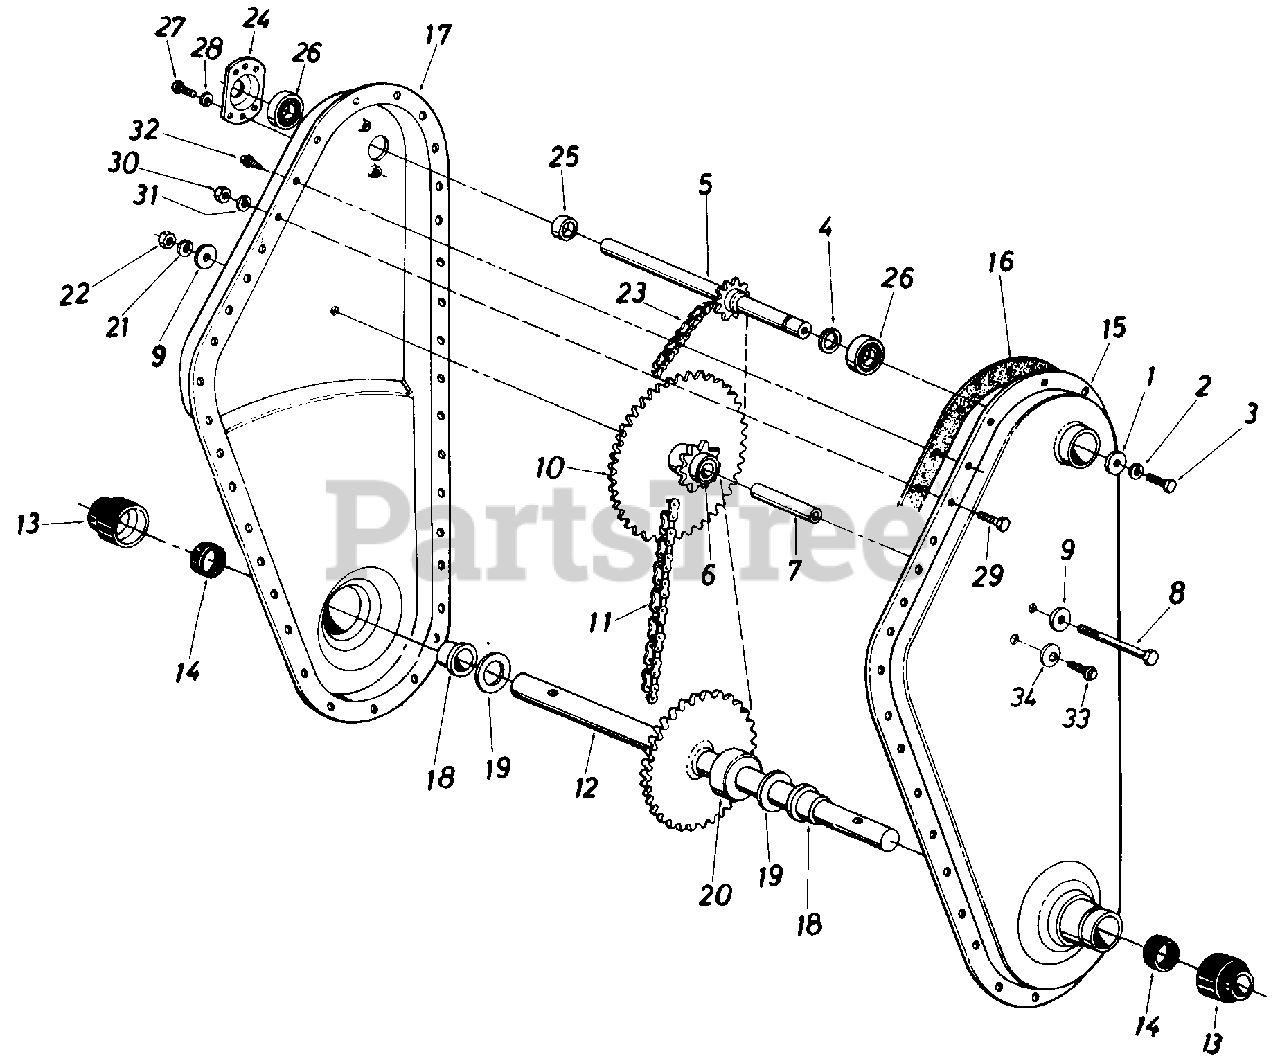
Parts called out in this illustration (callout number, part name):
1	Fl-Wash. 1/4" l.D. x .93" O.D. x .120
2	L-Wash. 1/4" I.D.
3	Hex Bolt 1/4-28 x .62" Lg. w/Patch
4	Extemal Snap Ring-5/8" Dia.
5	Input Shaft Ass'y.
6	Bearing 618" l.D. x 3/4" O.D. x 1.860" Lg.
7	Sprocket Hub Tubing 3/8" l.D. x 618" O.D. x 1.90
8	Hex Bolt 3/8-24 x 2 75" Lg.
9	Fl-Wash. 3/8" l.D. x 1.25" O.D. x .10
10	Sprocket Ass'y.
11	#50 Chain 5/8" Pitch x 46 Links Endless
12	Tine ShaR Ass'y.
13	Dust Cup
14	Seal Ring Single Lip, Springless
19	Fl-Thrust Wash. 1.0" I.D. x .03 Thk.
20	Step Spacer
21	L-Wash. 3/8" I.D.
22	Hex Nut 3/8-24 Thd.
23	#35 Chain 3/8" Pitch x 52 Links Endless
24	Bearing Housing 1.38" I.D.
25	Spacer
26	Ball Bearing .625" l.D. x 1.38 O.D. x .437
27	Hex Wash. SF-Tap Scr. 1/4-20 x .501' Lg.
28	L-Wash. 1/4" l.D.
29	Hex Bolt 5/16-18 x .75" Lg.
30	Hex Nut 5/16-18 Thd.
31	L-Wash. 5/16" I.D.
32	Hex Wash. SF-Tap Scr. 1/4-20 x 50" Lg
33	Hex Wash. Hd. Tap Scr. 1/4-20 x.38" Lg.
34	Bell-Wash. .265" I.D. x .75" O.D.
